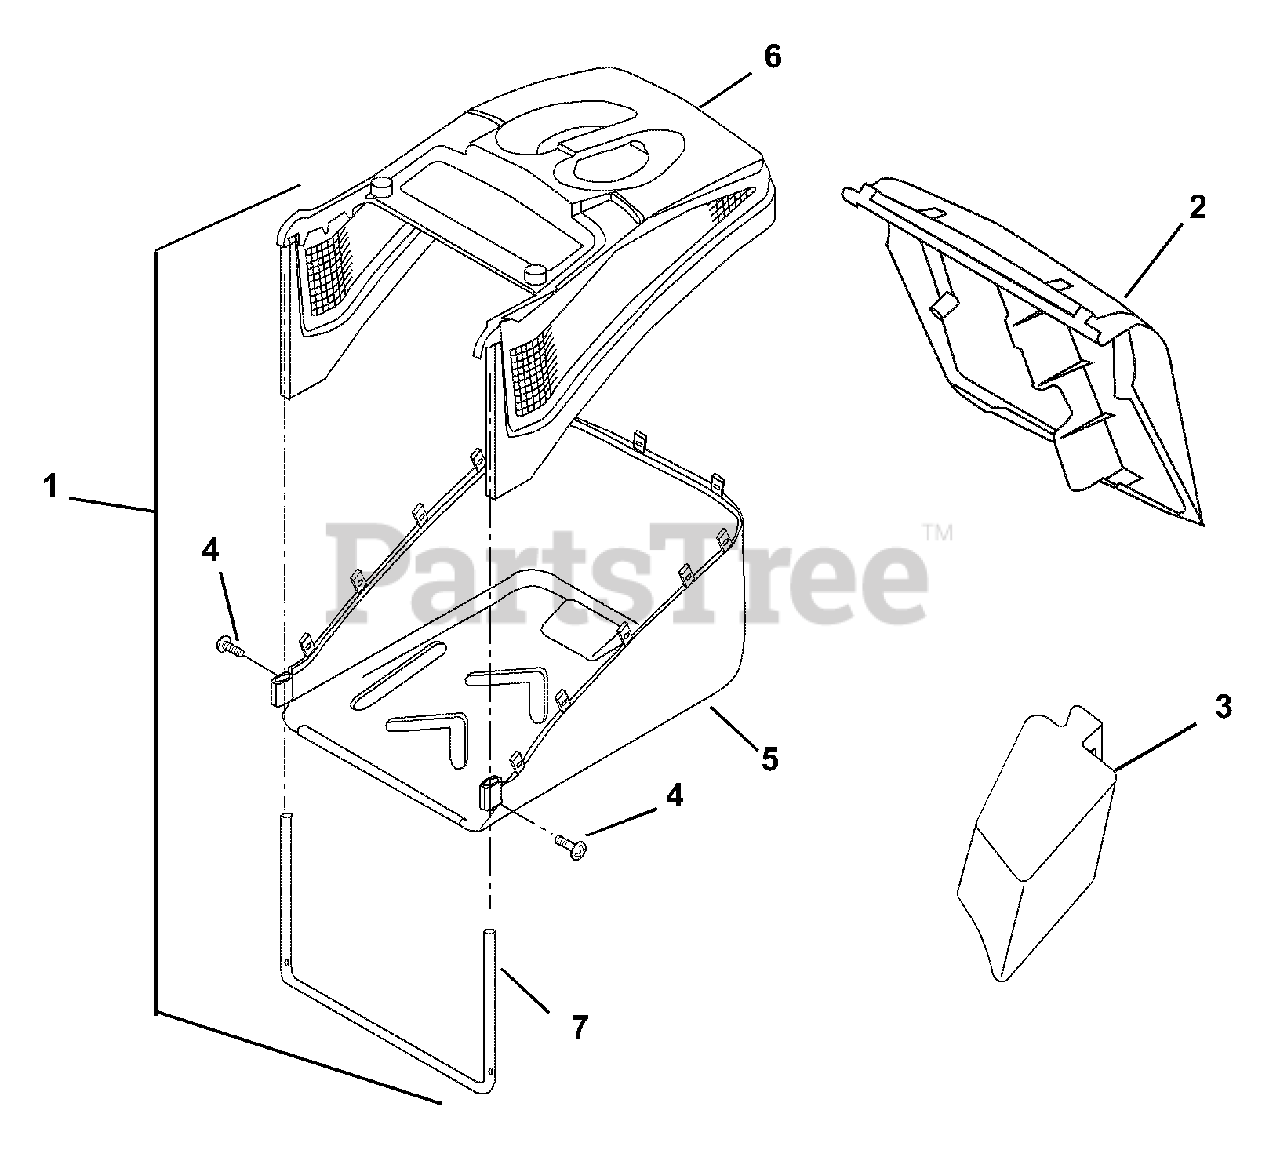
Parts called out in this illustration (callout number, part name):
1	BAGGER, GRASS
2	DOOR, W/DECAL IMPORT
3	PLUG, MULCHING
5	GRASS BOX, LOWER -IMPORT ALUM
6	GRASS BOX, UPPER - IMPORT ALUM
7	SUPPORT, FABRIC BOX WIREFORM
